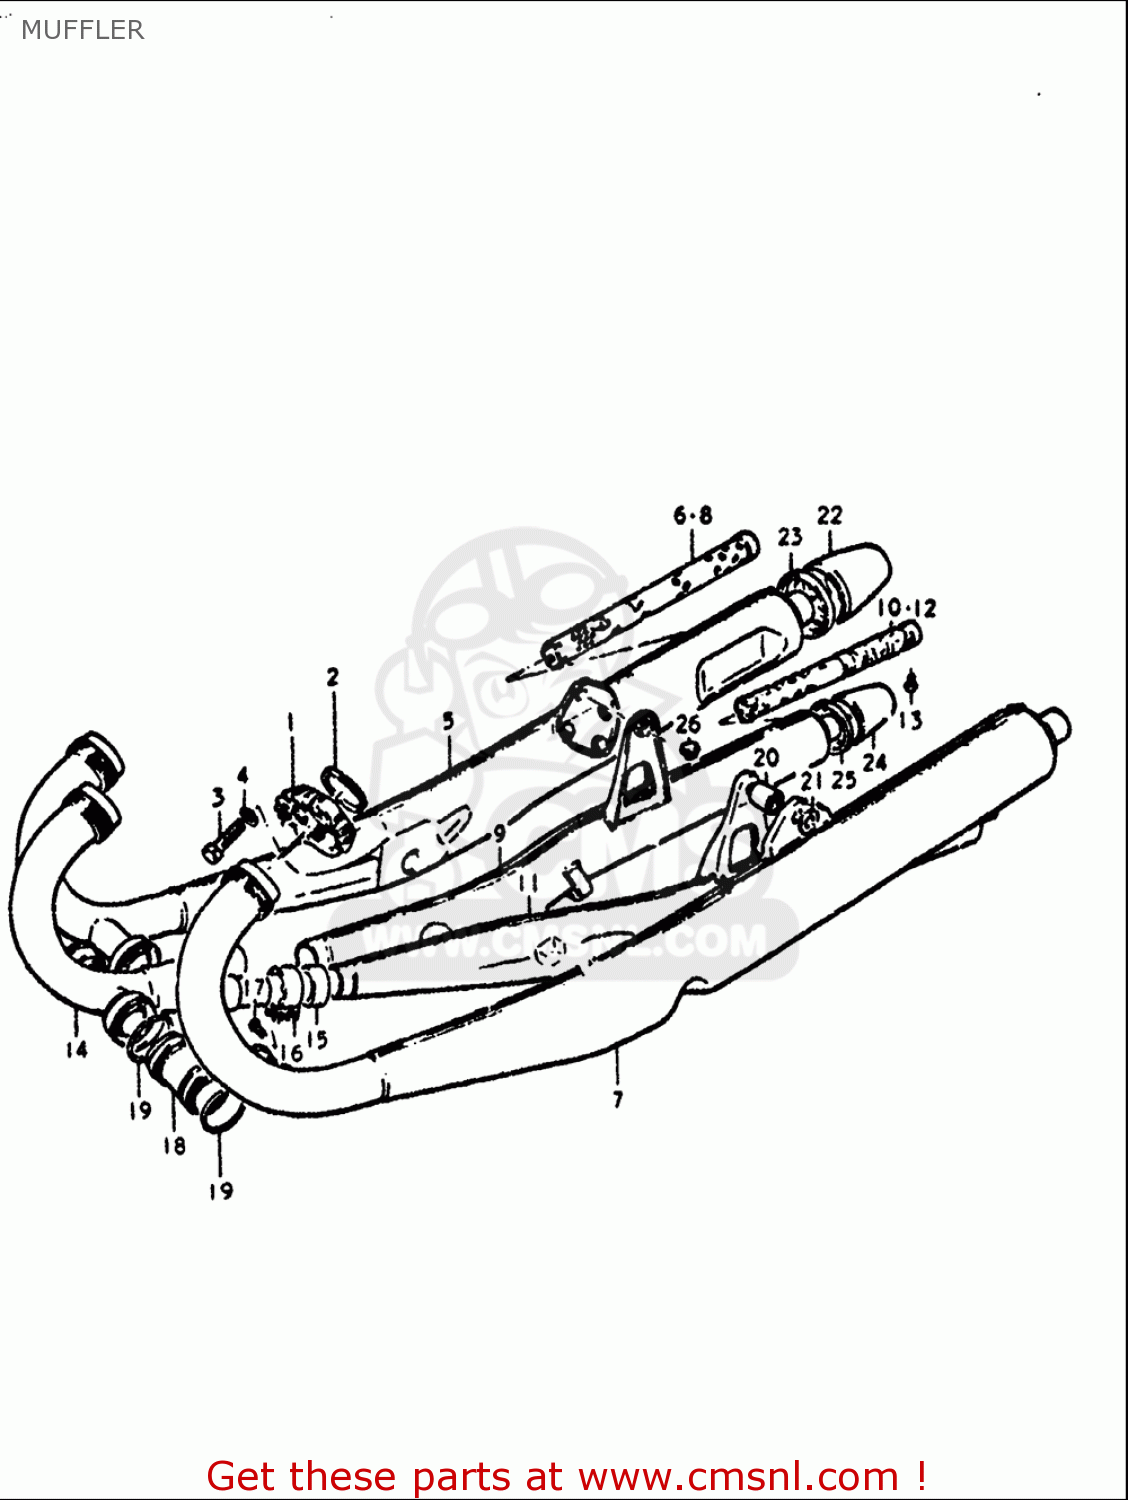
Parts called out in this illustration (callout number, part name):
2	GASKET,EXHAUST PIPE (NAS)
3	BOLT
4	WASHER,LOCK
6	PIPE,BAFFLE
8	PIPE,BAFFLE
10	PIPE,BAFFLE CTR
12	PIPE,BAFFLE CTR
13	SCREW(5X6)
15	CONNECTOR,MUFFLER
17	SCREW
19	O RING(D:2.6,ID:39.7)
20	BUSH
21	WASHER
25	CLIP, REAR COVER CENTER
26	CUSHION
